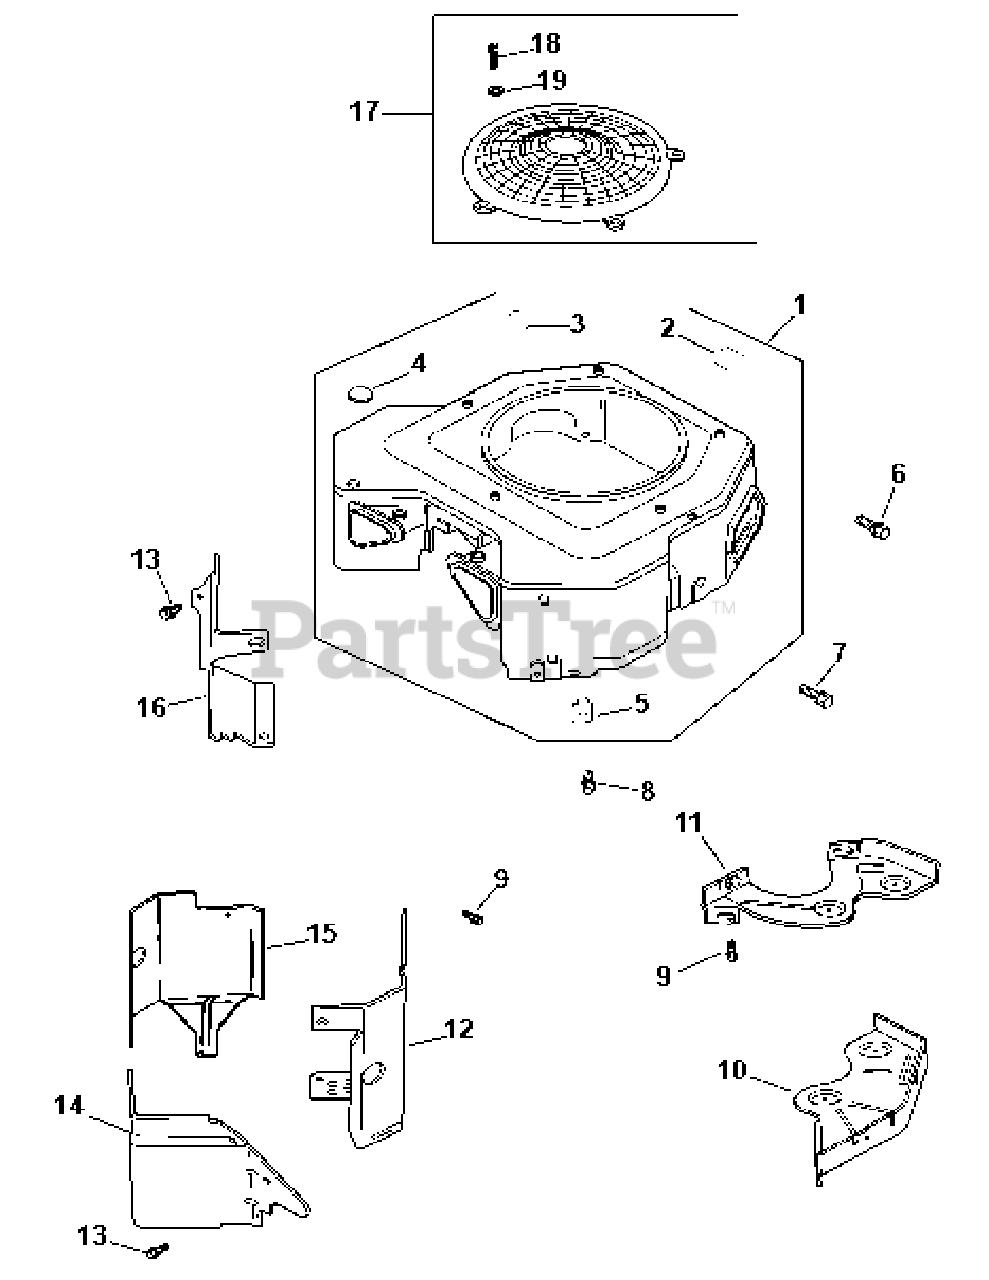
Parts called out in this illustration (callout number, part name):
1	Blower Housing
2	Plastic Nut
3	Tapping Screw
4	9/16" Button Plug
6	Screw
8	Screw
10	Backing Plate # 2
11	Backing Plate # 1
12	Cylinder Barrel Baffle # 2 Side
14	Valley Baffle # 2 Side
15	Cylinder Barrel Baffle # 1 Side
16	Valley Baffle # 1 Side
17	Fixed Guard Kit
18	Pan Head Screw
